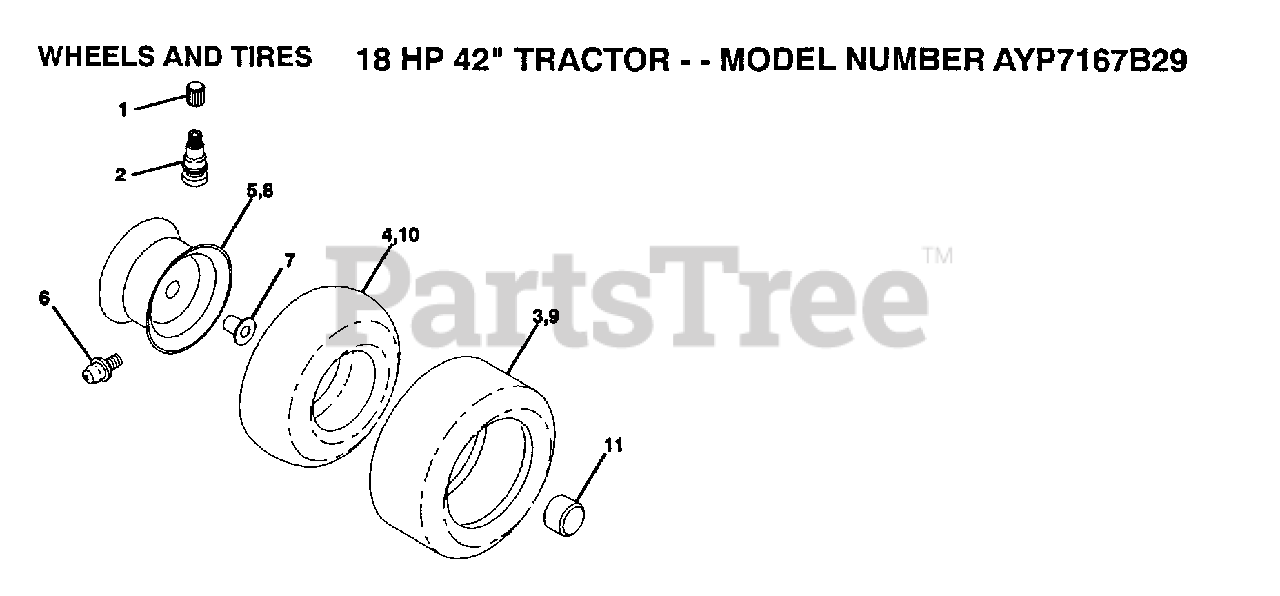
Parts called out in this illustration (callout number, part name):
1	VALVE CAP
2	VALVE STEM LT
4	TUBE.5.3/4.5/6
6	FITTING LT
7	"FLANGE, BEARING"
10	TUBE.18X9.5-8
11	HUB CAP
